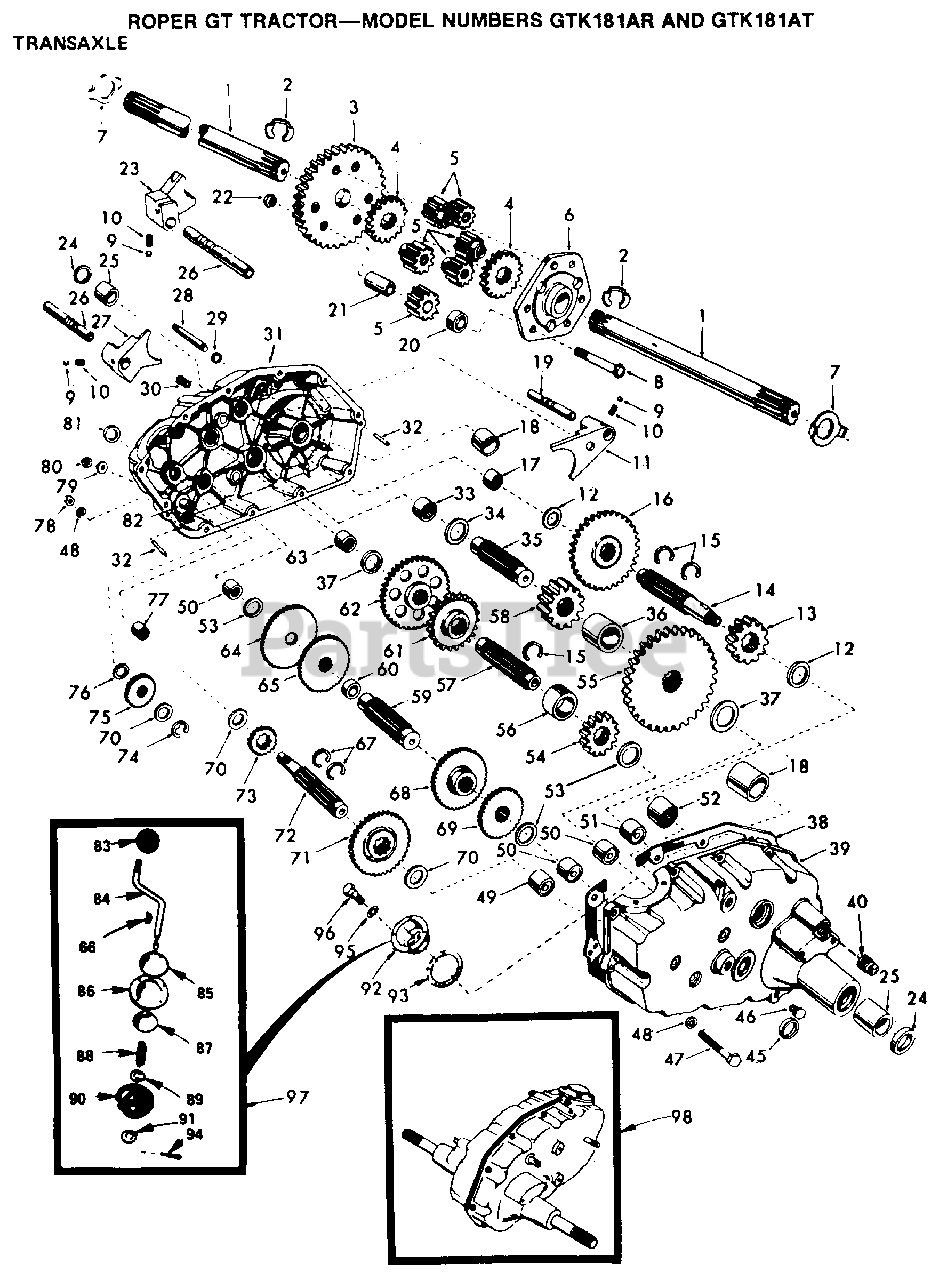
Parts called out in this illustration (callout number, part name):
1	SHAFT.AXLE.T
3	FINAL GEAR T
4	DIFF GEAR T
5	DIFF PINION T
6	DIFF CARRIER T
8	BOLT
11	SHIFT FORK T
12	WASHER .T
13	RED PINION T
14	GEAR SHAFT T
15	SNAP RING T
16	GEAR T
17	"T, BEARING"
18	BEARING
20	SPACER T
21	PINION RS
22	GRIPCO NUT
23	SHIFT FORK T
24	OIL SEAL STD
25	BRNG. T
27	FORK T
28	SHIFT SHAFT GTV
29	SEAL T
30	VALVE M
32	PIN T
33	NEEDLE BRNG T
34	RACE T
35	GEAR SHAFT T
37	RACE T
45	SEAL T
47	HEX BOLT
49	"TI, BEARING"
50	NEEDLE BRNG T
51	NEEDLE BRNG T
52	"STD, BEARING"
53	BRNG RACE
54	RED PINION T
55	RED GEAR T
56	PINION SPACER T
57	GEAR SHAFT T
58	FINAL PINION T
59	GEAR SHAFT T
60	SPACER T
61	RED PINION T
62	RED GEAR T
63	RACE T
64	LOW SPEED GEA T
65	REVERSE GEAR T
66	KEY T
67	RING STD
68	INTERMED GEAR T
70	"T, BEARING"
71	CLUSTER GEAR T
72	INPUT SHAFT T
73	LO SPEED PINION T
75	IDLER GEAR T
76	WASHER T
77	BRNG T
78	NUT.HEX.5/16-18
79	WASHER T
80	NUT
81	SEAL STD
84	GEAR SHIFT LVR T
85	CAP T
86	COVER AND PIN T
87	GUIDE BALL T
88	SPRING TI
89	WASHER
90	SEAL T
91	WASHER
92	GEAR SHIFT GA T
93	GASKET T
94	COTTER PIN
95	LOCKWASHER
96	BOLT
97	GEAR SHFT LVR T
98	TRANSAXLE GTV
